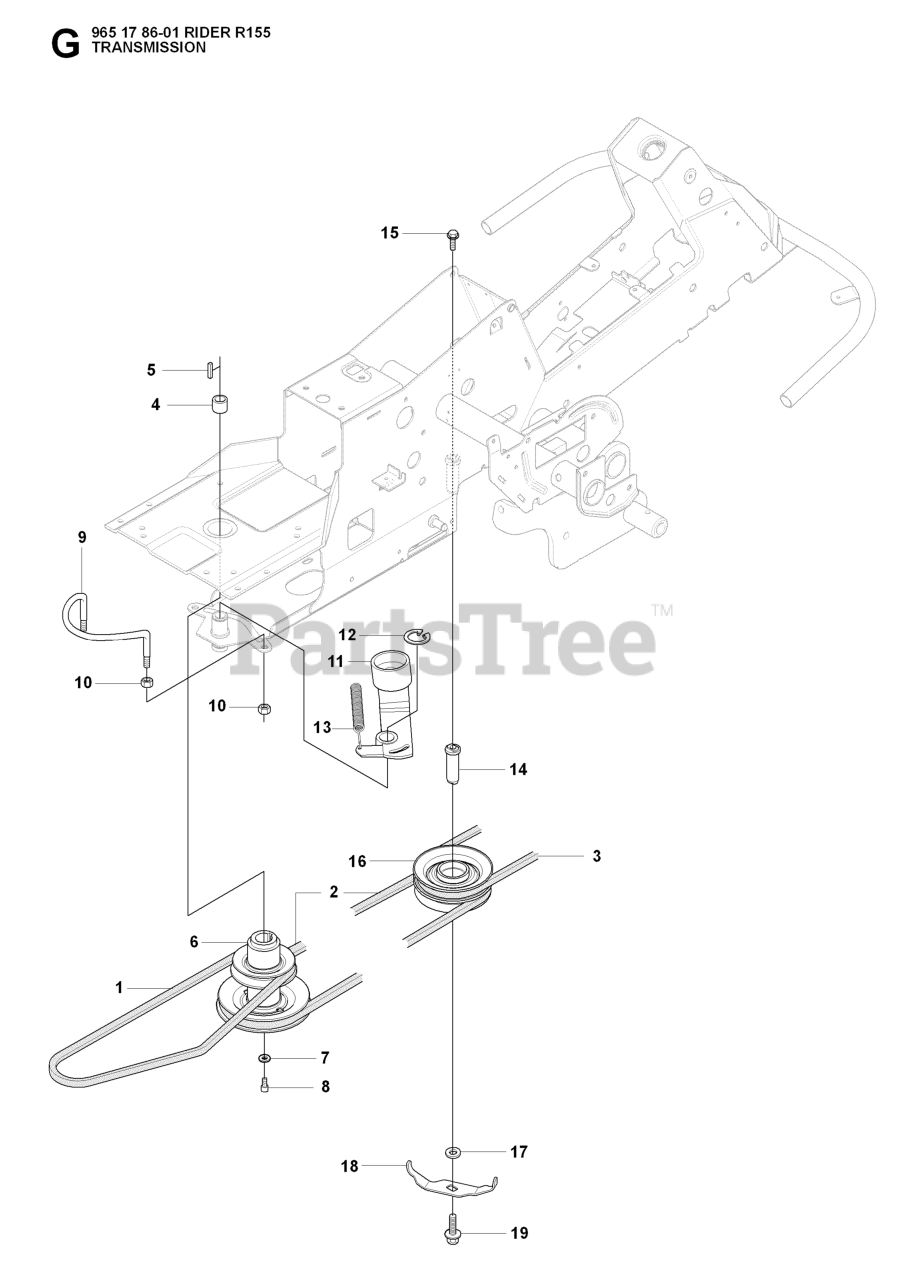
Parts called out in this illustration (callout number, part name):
1	BELT
2	BELT
9	BELT GUIDE
10	NUT
12	RETAINING RING SGA 25
14	SHAFT
18	BELT GUIDE
19	BOLT
